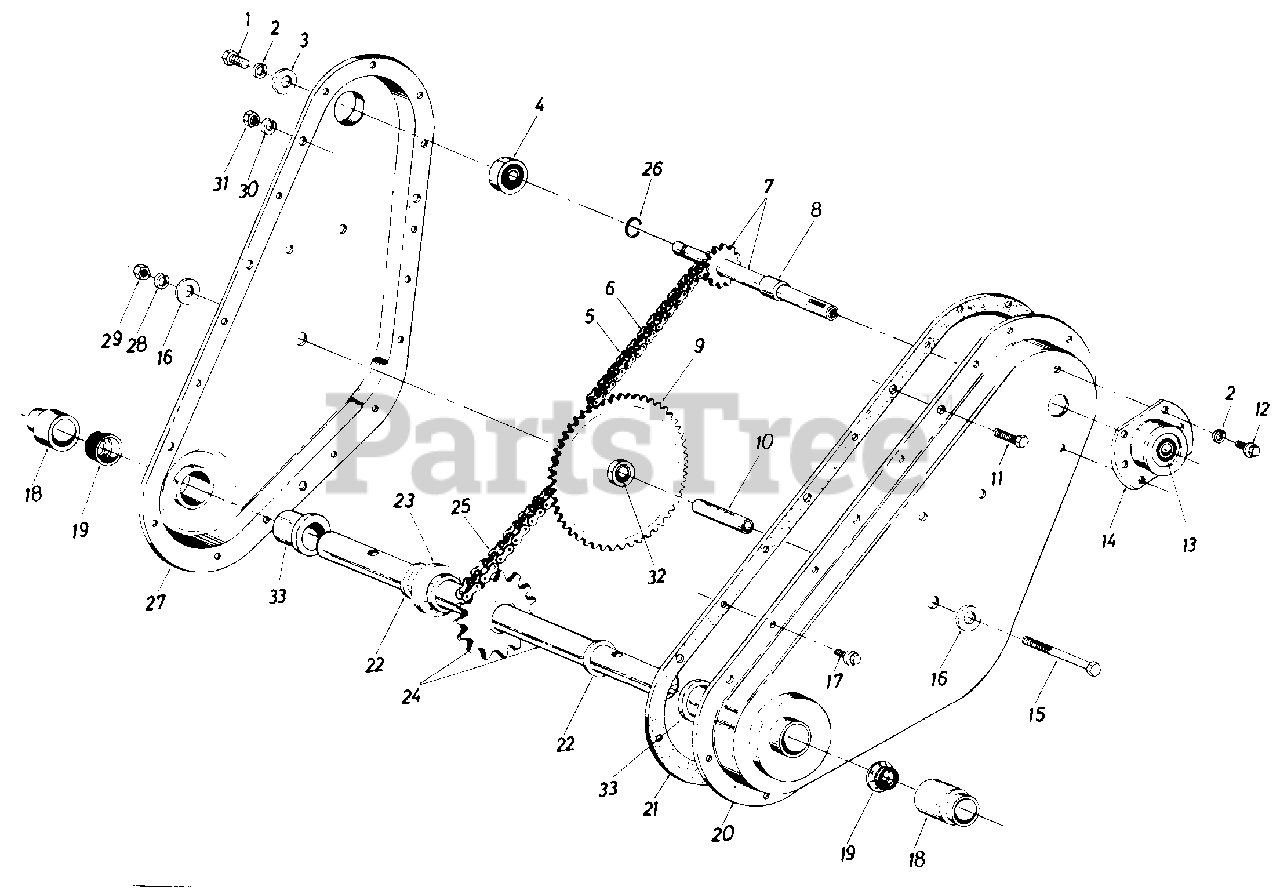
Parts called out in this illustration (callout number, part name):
1	Hex L-Scr. 1/4-28 x .625" Lg.
2	L-Wash. 1/4" Scr.
3	Fl-Wash. .25" I.D. x .93" O.D. x .125" Thk.
4	Bearing .62" I.D. x 1.38" O.D. x .437" Thk.
5	#35 Chain 3/8" Pitch x 52 Links Endless
6	Master Link
7	Input Shaft Assembly
8	Spacer
9	Sprocket Assembly
10	Sproekct Hub Tubing 3/8" I.D. x 5/8" O.D. x 1.9" Lg.
11	Hex Scr. 5/16-18 x .625" Lg.
12	Hex Wash. Hd. Self-Tap Scr. 1/4-20 x .50" Lg.
13	Bearing .625" I.D. x 1.38" O.D. x .437" Thk.
14	Bearing Housing
15	Hex Scr. 3/8-24 x 2.75" Lg.
16	Fl-Wash. 3/8" I.D. x 1.25" O.D. x .100 Thk.
17	Hex Wash. Hd. Self-Tap Scr. 1/4-20 x .50" Lg.
18	Dust Cap
22	Thrust Wash. 1.00 I.D. x .030" Thk.
23	Step Spacer
24	Tine Shaft Assembly
25	#50 Chain 518" Pitch x 46 Links Endless
26	Snap Ring 518" Dia. Shaft
29	Hex Nut 3/8-24 Thd.
30	L-Wash. 5/16" Scr.
31	Hex Nut 5/16-18 Thd.
32	Bearing
33	Bearing
